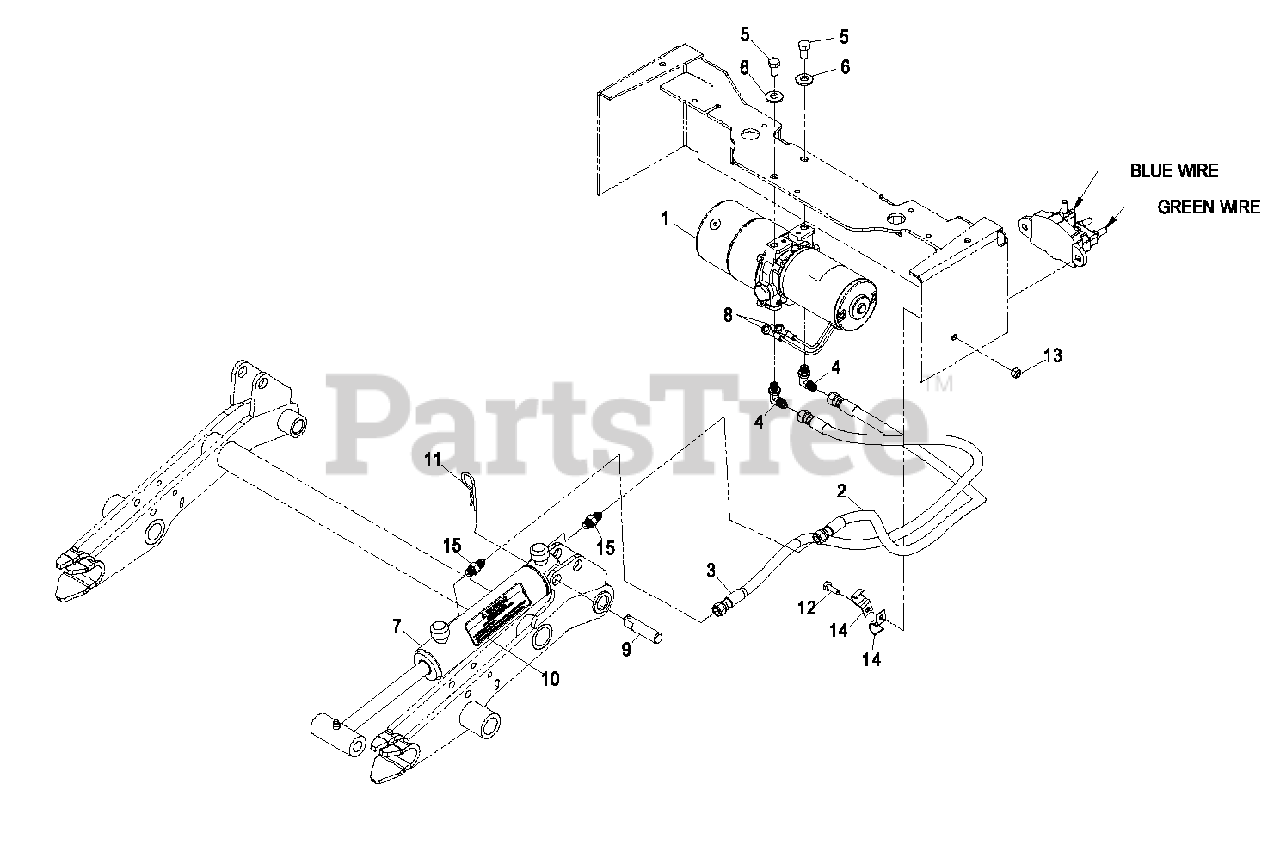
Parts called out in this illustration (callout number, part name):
2	ASM,HYDRAULIC HOSE -4
3	ASM,HYDRAULIC HOSE -4
4	ADAPTER,90 DEG
4	O-RING,-4 FLARE-O(SERVICE
5	SCREW-HH
6	WASHER-BELLEVILLE
7	ASM,FMZ HYD CYLINDER
7	KIT,FMZ HYD CYLINDER SEAL
8	TERMINAL,RING 5/16" INSUL
9	PIN,CYLINDER MOUNT RR
10	DECAL,HIGH PRESSURE OIL
11	PIN-COTTER
12	SCREW-HH
13	NUT-LOCK, NI
14	CLIP-HALF, LOOM
15	ADAPTER,STRAIGHT ORIFICED
15	O-RING,-4 FLARE-O(SERVICE
